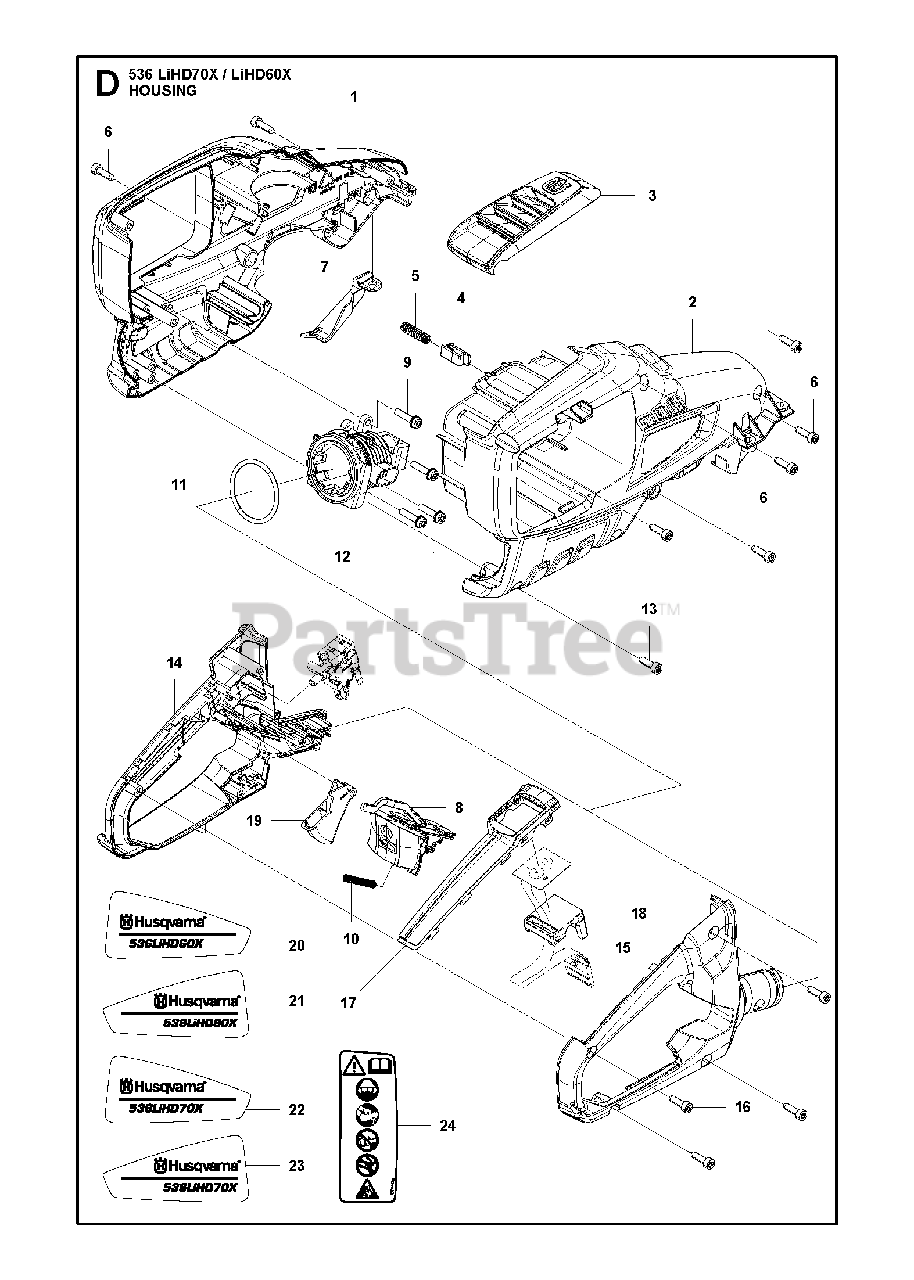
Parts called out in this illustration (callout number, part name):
1	CHASSIS LEFT
2	CHASSIS RIGHT
3	COVER CHASSIS
4	PUSH BUTTON
5	SPRING
7	COVER WIRING
8	LOCKING BUTTON
9	SCREW IHSCFT
10	RECOIL SPRING RECOIL SPRING RE
12	HANDLE HOLDER
13	SCREW
14	REAR HANDLE LEFT
15	REAR HANDLE RIGHT
16	SCREW
17	FRAME KEYPAD
18	BRACKET KEYPAD
19	THROTTLE CONTROL
20	DECAL PRODUCT DECAL 536LIHD60X
21	DECAL PRODUCT DECAL 536LIHD60X
22	DECAL PRODUCT DECAL 536LIHD70X
23	DECAL PRODUCT DECAL 536LIHD70X
